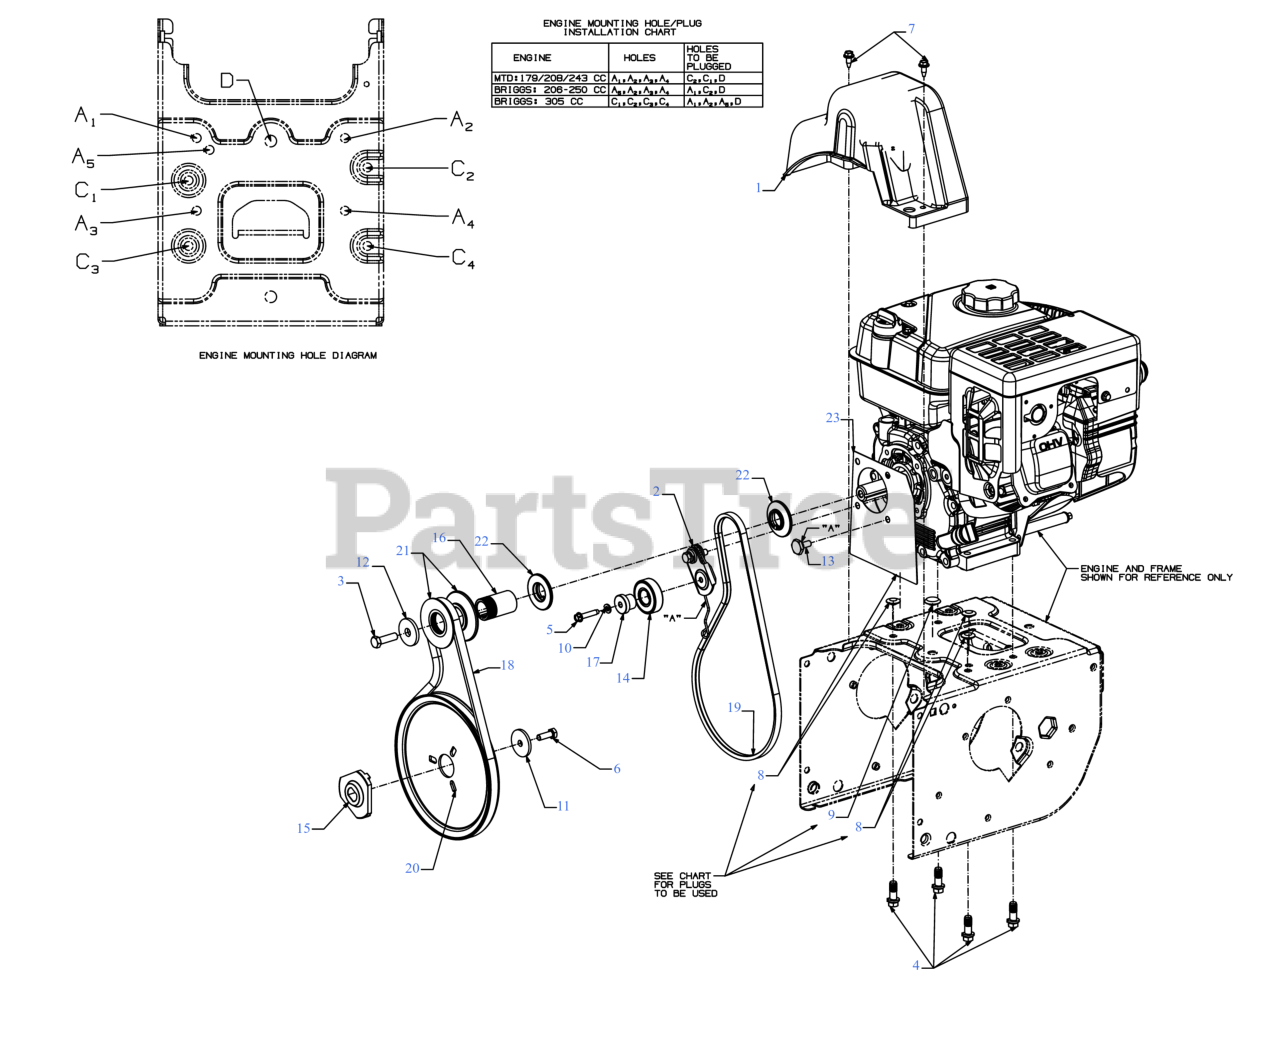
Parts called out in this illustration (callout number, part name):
1	BELT COVER (SMALL BLOCK)
3	SCREW 3/8-24X1.25
4	SCREW 3/8-16 x 1
5	SCREW 1/4-20 x 1.25
6	SCREW 5/16-24 x .875 GR5
7	SCREW 1/4-20X.625
8	PLUG-3/8 DIA ID x 3/32
9	PLUG-1/2 ID x 3/32
10	LOCK WASHER
11	FLAT WASHER
12	FLAT WASHER .45 x 1.5 x .172 HT
13	SHOULDER SCREW
14	BALL BEARING
15	ADAPTER PULLEY .75 DIA W/DD
16	PULLEY SPACER
17	SHOULDER SPACER
18	V-BELT .500 x 35.00LG
18	Cub Cadet AUGER BELT
18	Genuine Factory Parts AUGER BELT
19	V-BELT 3L 34.18
19	Cub Cadet TRANSMISSION BELT
19	Genuine Factory Parts TRANSMISSION BELT
20	AUGER PULLEY
21	HALF PULLEY 4L V x 2.6 OD
22	HALF PULLEY-3/8 V x 1.7160
